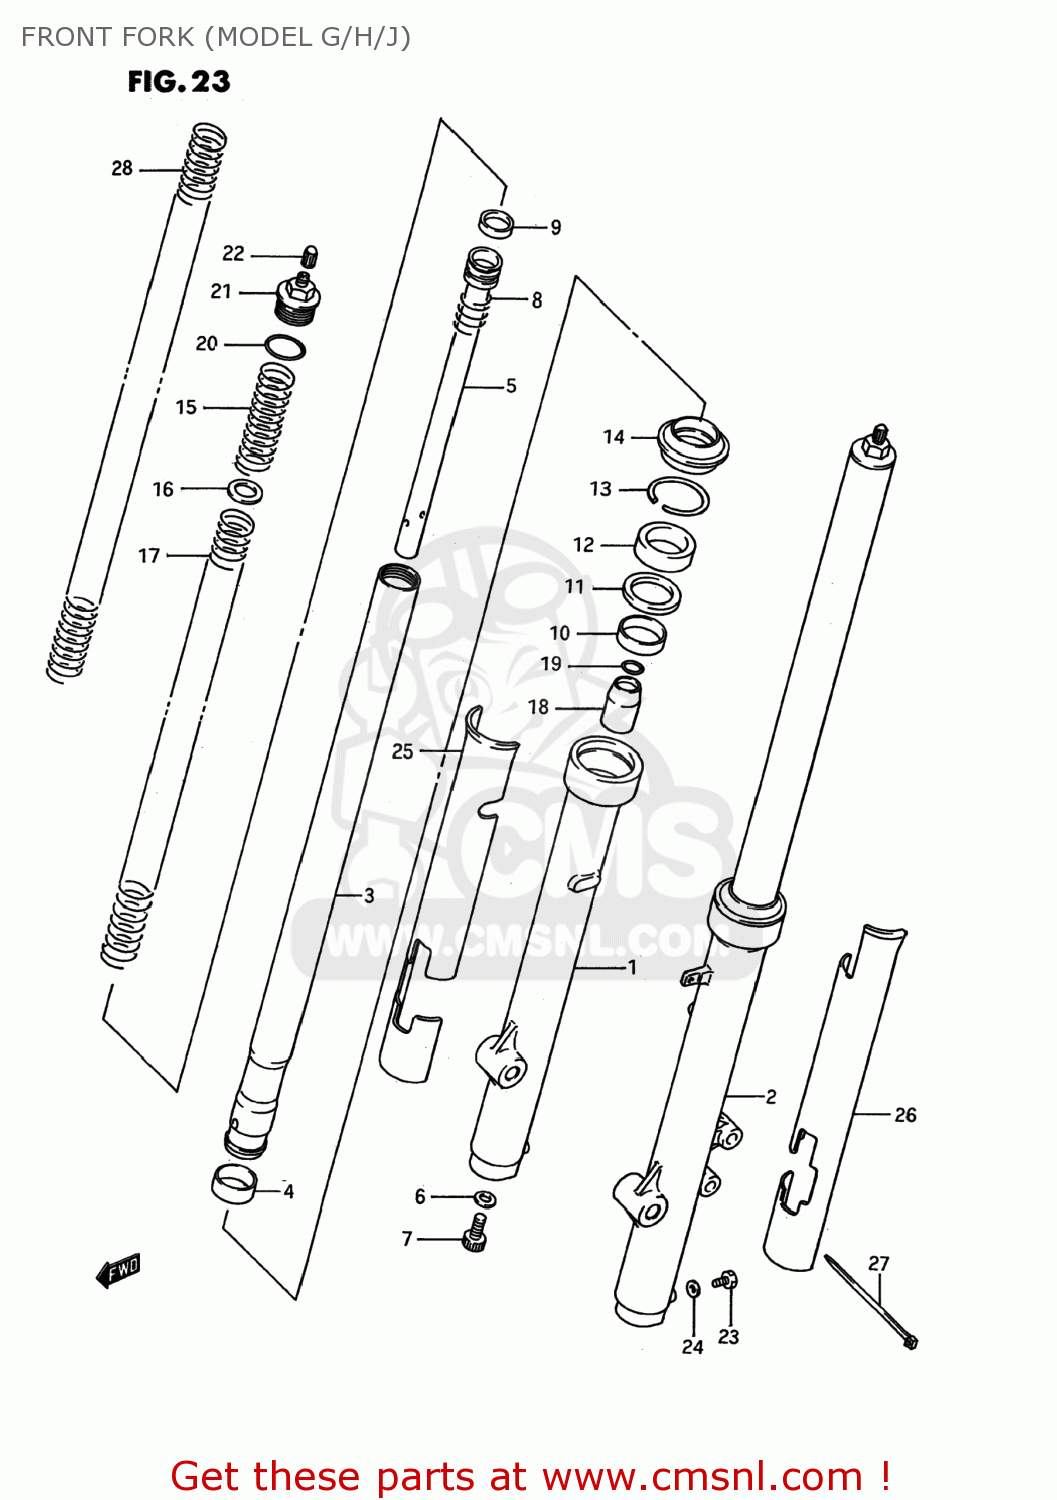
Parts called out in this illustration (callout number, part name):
1	TUBE,OUTER,RIGHT
2	TUBE,OUTER,LEFT
3	TUBE,FORK,INNER
4	PISTON
5	CYLINDER,FRONT FORK
6	GASKET,FORK CYLINDER (NAS)
7	BOLT
8	SPRING,REBOUND
9	RING,FRONT FORK PISTON
10	BUSH,GUIDE
11	SEAL,SPACER
12	SEAL,OIL
13	RING,OIL SEAL STOPPER
14	DUST SEAL,FRONT FORK
15	SPRING,FRONT FORK
16	SPRING,JOINT
17	O-RING
18	PIECE,FRONT FORK OIL LOCK
19	RING,STOPPER
20	O RING
21	BOLT,FORK INNER TUBE
22	CAP
23	BOLT
24	GASKET,DRAIN,PLUG (NAS)
25	PROTECTOR,FR FORK,R
26	PROTECTOR,FR FORK,L
27	CLAMP
28	SPRING,FRONT FORK
